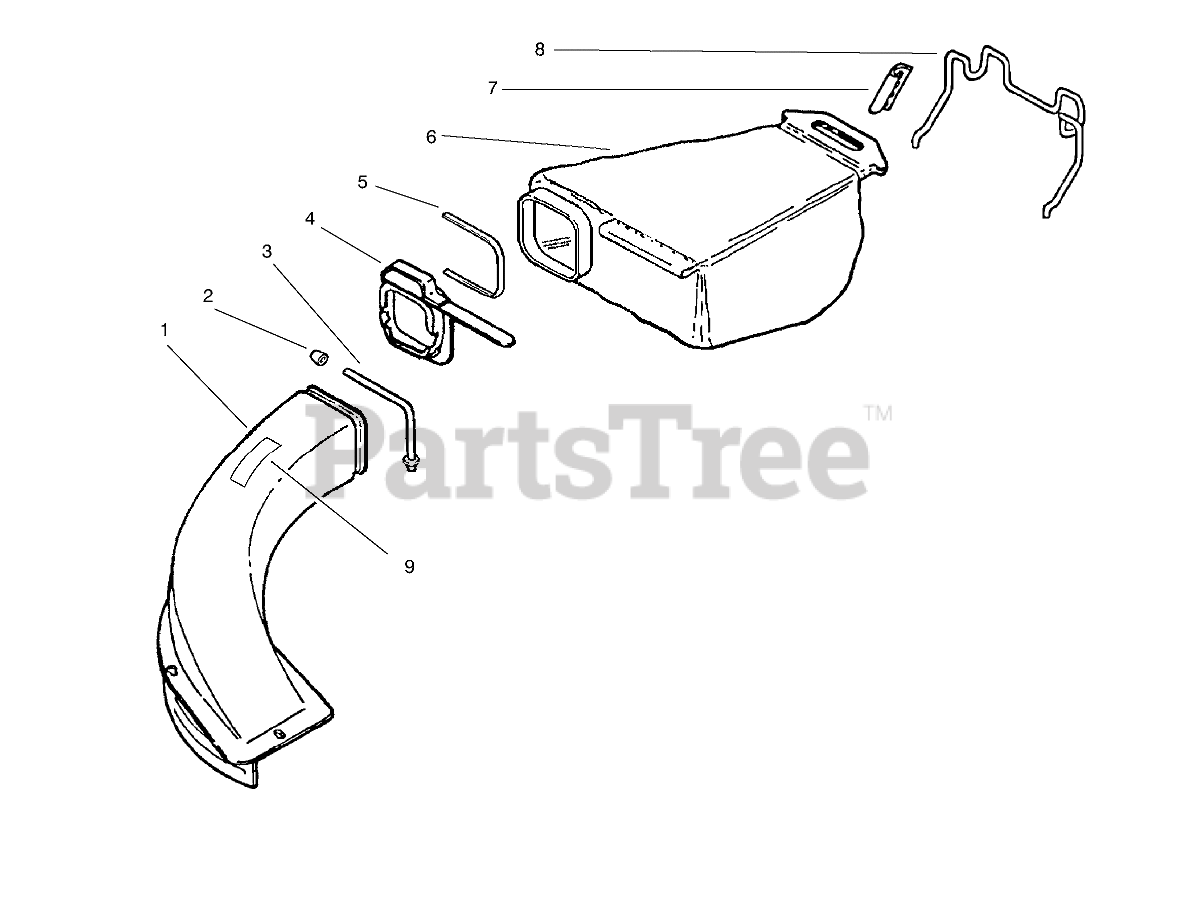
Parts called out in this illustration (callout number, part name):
1	Chute & Support Assembly (Incl. Ref. #2, 3, & 9)
2	NUT-CAP
3	SUPPORT-CHUTE
4	ASM-Adapter
5	STRAP-TIE
6	BAG - GRASS
7	Bracket
8	HANGER-WIRE
9	DECAL - DANGER
